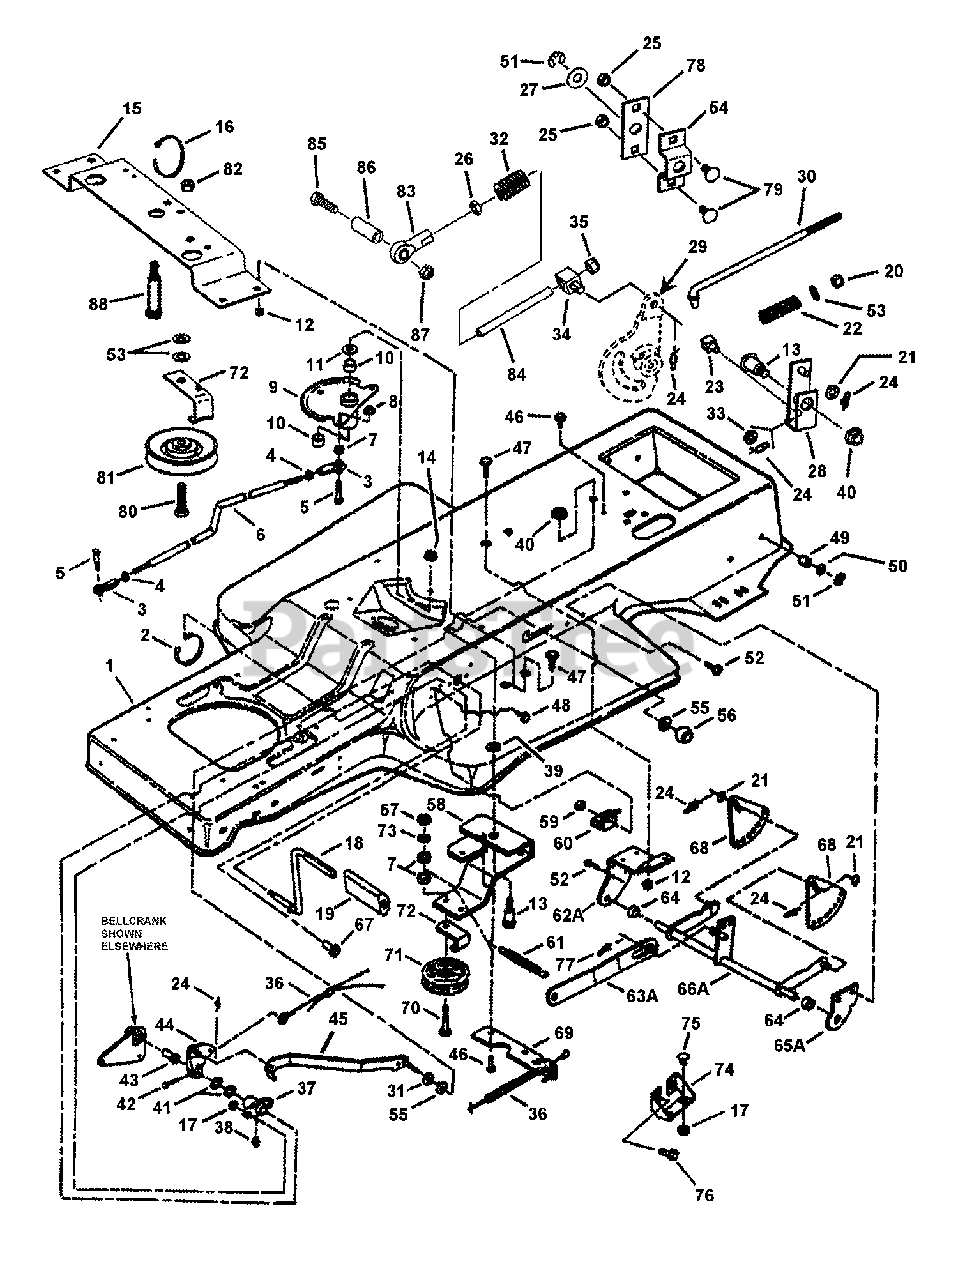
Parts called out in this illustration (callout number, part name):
1	FRAME, Tractor (I piece)
2	CABLE TIE, 3.19
3	BALL JOINT, Pump Control Linkage, 3/8-24 thread
4	NUT, 3/8-24 Hex Jam
5	SCREW, 3/8-24 x 1-1/4" Square Neck Carriage
6	DRAGLINK
7	SPACER, Tie Rod
8	NUT, 3/8-16 Hex Flange Lock
9	ASSEMBLY, Steering Sector (Includes 41267, Weldment & item 10)
10	BEARING, Sleeve, .875 0.D. x .75
11	THRUST WASHER
12	NUT, 1/4-20 Hex Flange Lock
13	SHOULDER BOLT, 1/2-13 thread
14	NUT, 1/2-13 Hex Center Lock, GR A
15	BRACE, Sector Gear
16	CABLE TIE, 7"
17	NUT, 5/16-18 Hex Flange Lock, GR5
18	PEDAL, Clutch/Brake
19	PEDAL PAD
20	NUT, 3/8-16-3B Hex Nyloc
21	WASHER, 3/8" Flat SAE
22	SPRING, Brake
23	SWIVEL, Inline Brake Arm
24	COTTER PIN, 3/8 x 1-7/32" Self Lock
25	NUT, 5/16-18 Hex Center Lock, GR5 or B
26	NUT, 5/16-24 Hex Jam
27	WASHER, .44" I.D. Flat
28	WELDMENT, Brake Bellcrank
29	ARM, Speed Control (Component of Transaxle, see Transmission Page)
30	ROD, Brake- K46
31	WASHER, 5/16 x .11/16 x .08 Flat
32	SPRING, Rectangular Wire Die, Blue
33	WASHER, 13/32 x 3/4" Flat
34	SWIVEL, Shift Linkage- PM
35	NUT, 5/16-24 Hex Nyloc
36	CABLE, Clutch/Brake- K46
37	ASSEMBLY, Pivot-Foot Shaft (Includes item 38)
38	LUBE FITTING, Straight (press-fit for .187 dia. Hole)
39	WASHER, 1/2" Internal Tooth Lock
40	NUT, 1/2-13 Hex Flange Lock
41	WASHER, .64 x .99 x .05 Flat
42	PIN, 3/16 x 1-1/2" Clevis
43	BEARING, Flange
44	ASSEMBLY, Clutch/Brake Arm
45	WELDMENT, Parking Brake, OPPLT
46	SCREW, 5/16-18 x 5/8" Hex Washer Self-Tap
47	BOLT, 1/4-20 x 5/8" Flat Head Square Neck, GR2
48	SCREW, #10-32 x 5/8" Hex Washer Head Machine, GR5
49	BUSHING, 1/2" Nylon
50	WASHER, .531 x 1.062 x .121 Flat SAE
51	RING, 1/2" External Retaining
52	SCREW, 5/16-18 x 5/8" Truss Head (Torx)
53	WASHER, 3/8" Flat
54	BRACKET, Pivot Mounting
55	WASHER, 5/16 Nylon
56	KNOB, Brake/Clutch- 5/16-18 thread
57	NUT, 3/8-16 Hex , GR5 or B
58	ARM, Idler-Traction Drive
59	NUT, #10-32 Hex Nyloc
60	SWITCH- DPDT
61	SPRING, Traction Drive
62A	BRACKET, Rear Lift/PTO Lever, Extruded
63A	LINK, Lift
64	SPACER, .515 x .688 x .403
65A	BRACKET, Deck Hang Pivot
66A	WELDMENT, Rear Lift Arm, 38/42
67	SCREW, 5/16-18 x 7/8" Truss Head (Torx)
68	SECTOR, Lift Plate
69	EXTENSION, Idler Arm
70	SCREW, 3/8-16 x 2-1/4" Hex Head Cap, GR5
71	PULLEY, 3.47 O.D. Flat Idler
72	BELT GUIDE, 3-1/2" Dia.
73	WASHER,3/8" Split Lock
74	*BRACKET, Frame Brace
75	*BOLT, 5/16-18 x 1/2" Short Neck Carriage, GR5
76	*SCREW, 5/16-18 x 3/4" Hex Washer Self-Tap
77	*PIN, 3/8 Self Lock Cotter
78	BRACKET, Mounting Brace
79	BOLT, 5/16-18 x 3/4" Square Neck Carriage GR5
80	SCREW, 3/8-16 x 1-1/2" Hex Head Cap, GR5
81	PULLEY, Idler V, 3.30 HA
82	NUT, 3/8-16 Hex Center Lock, GR5 or B
83	BALL JOINT, 5/16-24
84	ROD, Shift Linkage
85	SCREW, 5/16-18 x 1-1/2" Hex Head Cap, GR5
86	SPACER, .38 I.D. x .56 O.D. x .75 thick
87	NUT, 5/16-18 Hex Center Lock, GR5 or B
88	SHOULDER BOLT, 1/2-13 thread x 3"
